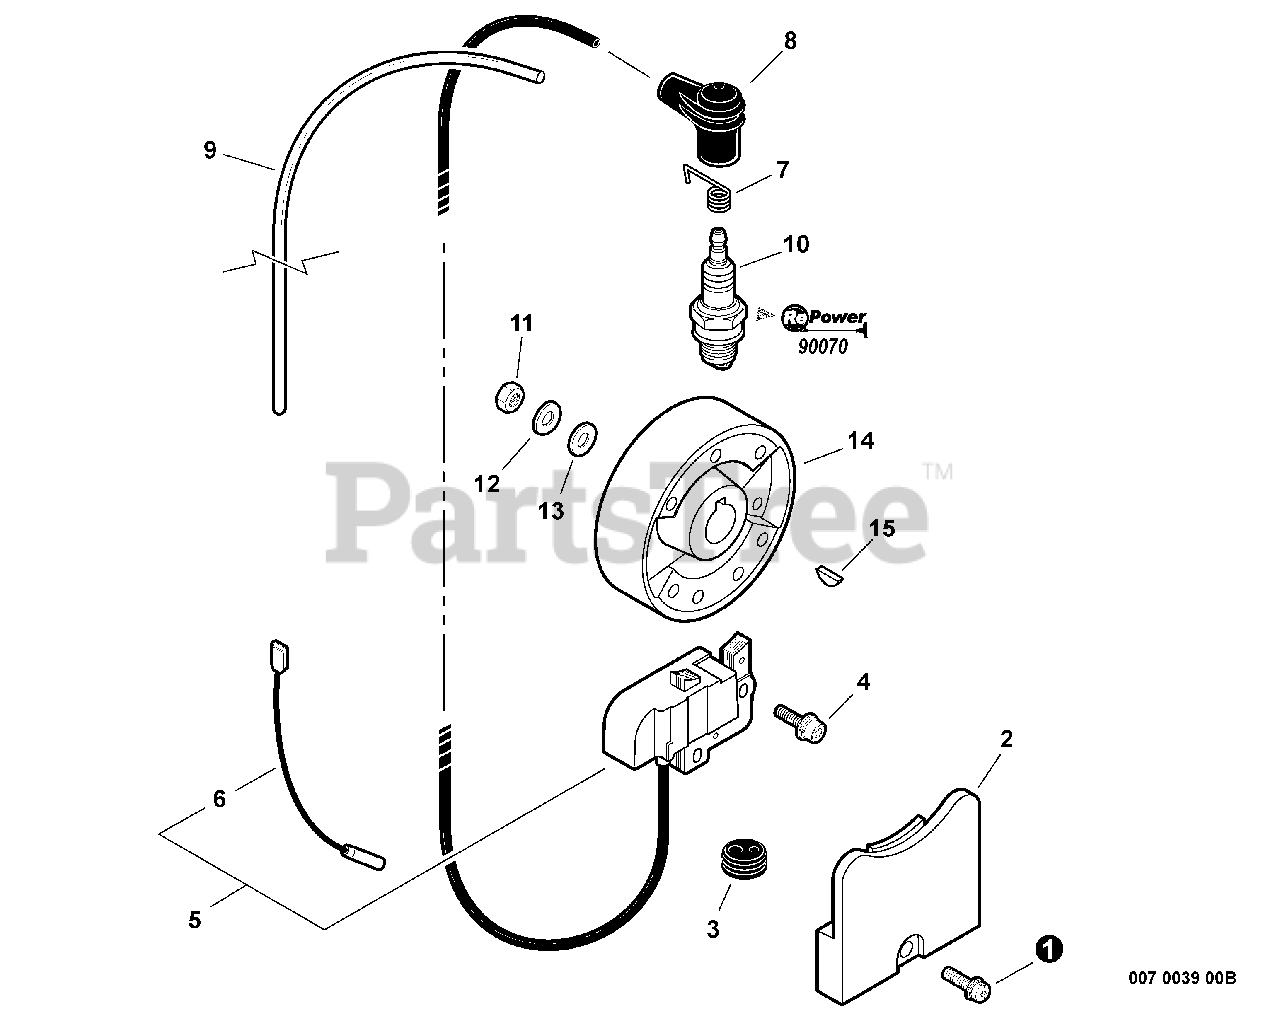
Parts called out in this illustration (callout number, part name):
1	SCREW 5×18
2	COVER, DUST
4	SCREW 5×18
5	COIL, IGNITION
6	LEAD - GROUND
7	TERMINAL, SPARK PLUG
8	CAP, SPARK PLUG
9	TUBE, VINYL 6.3×8×380
10	SPARK PLUG - BPM8Y
12	WASHER, SPRING 10
13	WASHER, SPRING 10
14	FLYWHEEL
15	KEY, WOODRUFF 3×14
16	TUNE-UP KIT - REPOWER
